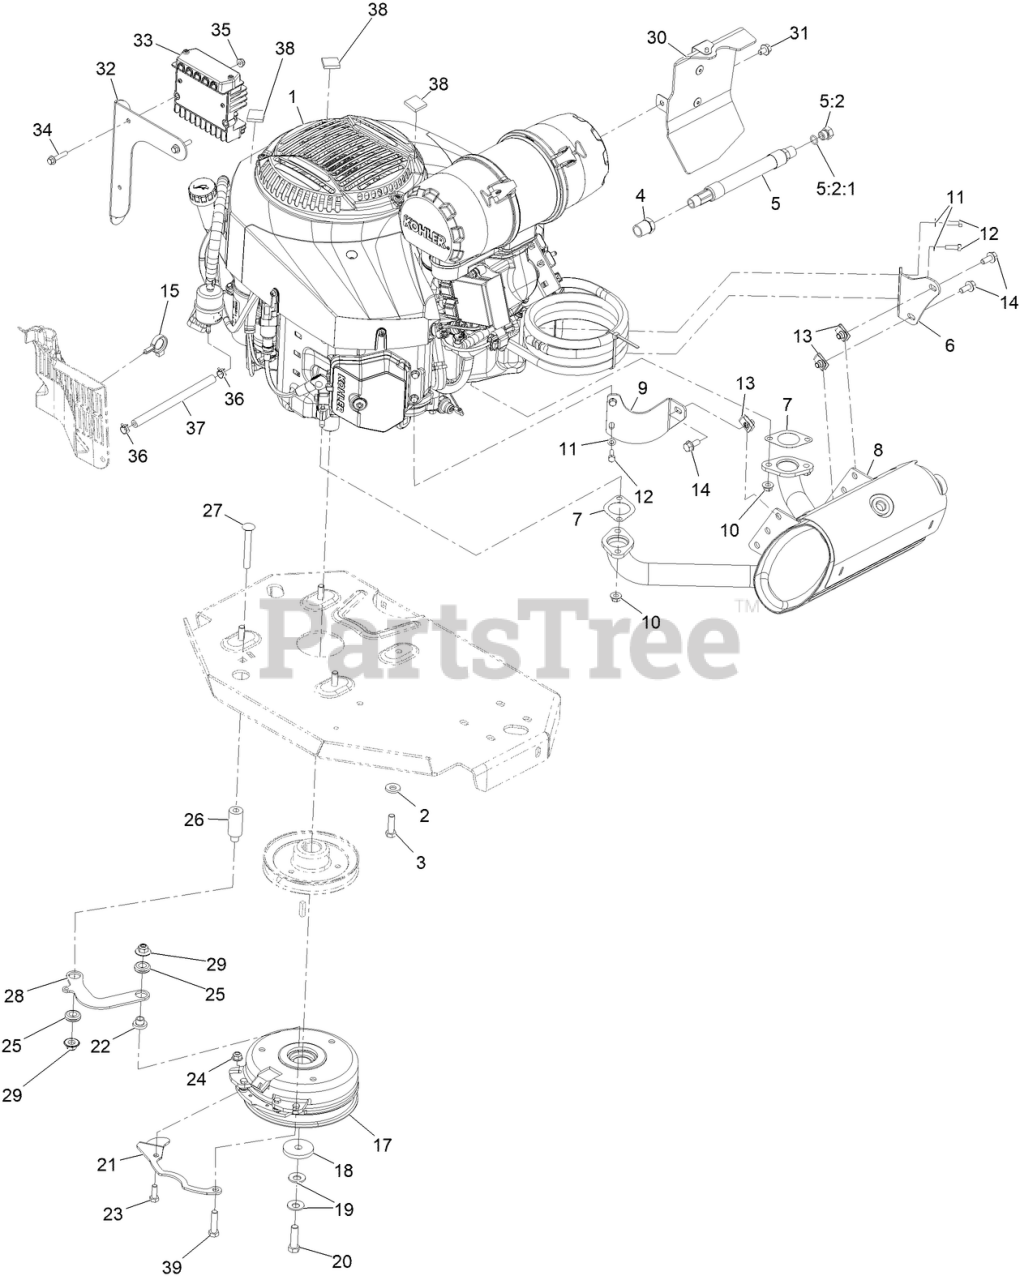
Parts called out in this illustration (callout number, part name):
2	WASHER-BELLEVILLE
3	SCREW-HH
4	BUSHING
5	OIL DRAIN HOSE ASM
5:2	PLUG-HH
5:2:1	O-RING
6	BRACKET-MUFFLER
7	GASKET-EXHAUST
8	MUFFLER-940-980 KOH EFI
9	BRACKET-MUFFLER, FRONT
10	NUT-FLANGE, LOCK
11	WASHER-SPRING
12	SCREW-HH
13	NUT-U
14	SCREW-HHF
15	CLAMP-HOSE
17	CLUTCH KIT
18	WASHER-CLUTCH
19	WASHER-SPRING
20	SCREW-HH, W/LOCTITE
21	BELT-GUIDE
22	SPACER
23	SCREW-HH
24	NUT-HF, NI
25	GROMMET-RUBBER
26	SPACER
27	SCREW-CARR
28	LINK-ANCHOR, CLUTCH
29	NUT-FLANGE, NI
30	BAFFLE ASM
31	SCREW-HHF
32	MOUNT-REGULATOR
33	REGULATOR AND RECTIFIER ASM
34	SCREW-HHF
35	NUT-HF
36	CLAMP-HOSE
37	HOSE-FUEL
38	VELCRO
39	SCREW-HH
